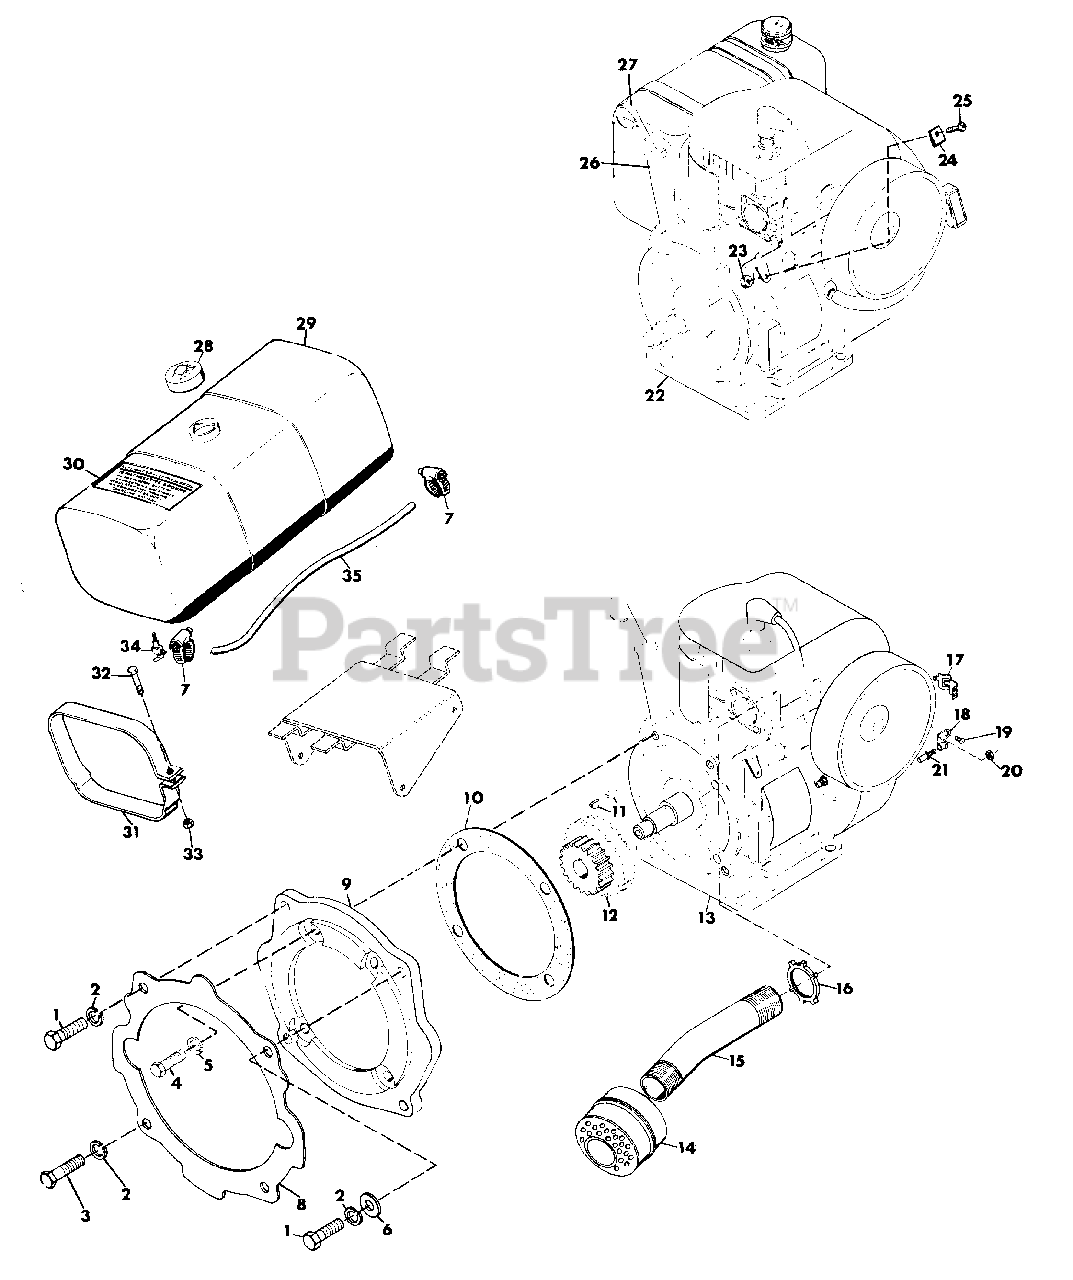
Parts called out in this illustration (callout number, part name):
1	BOLT, HEX 7/16-14X1.50
2	WASHER, LOCK 7/16 SP HEAVY
3	BOLT, HEX 7/16-14X1.25, 8 H.P.
3	BOLT, HEX 7/16-14X1.125, 12 H.P.
4	BOLT, HEX 3/8-16X.875, 8 H.P.
4	BOLT, HEX 3/8-16X1, 12 H.P.
5	WASHER, LOCK 3/8 SP HEAVY
6	WASHER, FLAT .469X.938X.065
7	CLAMP, HOSE(MODEL 5260, 5665, 5645)
8	GASKET, CHASSIS TO ADAPTOR
9	ADAPTOR, ENGINE 8 H.P.
9	ADAPTOR, ENGINE 12 H.P.
10	GASKET, ENGINE TO ADAPTOR 12 H.P.
10	GASKET, ENGINE TO ADAPTOR 8 H.P.
11	KEY, WOODRUFF 5/32X5/8 HARD
12	GEAR, 10/12 DP 21/30 TEETH
13	ENGINE, 12 H.P. 2-WHEEL ELECTRIC
13	ENGINE, 12 H.P. 2-WHEEL MANUAL
14	MUFFLER, 12 H.P.
15	TUBE, MUFFLER 12 H.P.
16	NUT, CONDUIT 1 PIPE
17	CLIP, SPEED
18	BRACKET
19	SCREW, MACH. 1/4-20X.50 PAN HD
20	NUT, HEX 1/4-20
21	ADAPTOR, CONDUIT
22	ENGINE, 8 H.P. 2-WHEEL MANUAL
22	ENGINE, 8 H.P. 2-WHEEL ELECTRIC
23	NUT, LOCK 10-24
24	CLIP
25	SCREW, MACH. 10-24X.50 PAN HD
26	TUBE, OIL FILL(MODEL 5260)
27	DIPSTICK(MODEL 5260)
28	CAP, GAS TANK(MODEL 5260, 5665, 5645)
29	ASSEMBLY, FUEL TANK
30	DECAL, E. S. WARNING MODELS 5260 AND 5665
31	STRAP, FUEL TANK(MODEL 5260, 5665, 5645)
32	BOLT, HEX 1/4-20X1.25(MODEL 5260, 5665,5645)
33	NUT, LOCK 1/4-20(MODEL 5260, 5665, 5645)
34	VALVE AND STRAINER(MODEL 5260, 5665, 5645)
35	LINE, FUEL(MODEL 5260, 5665, 5645)
